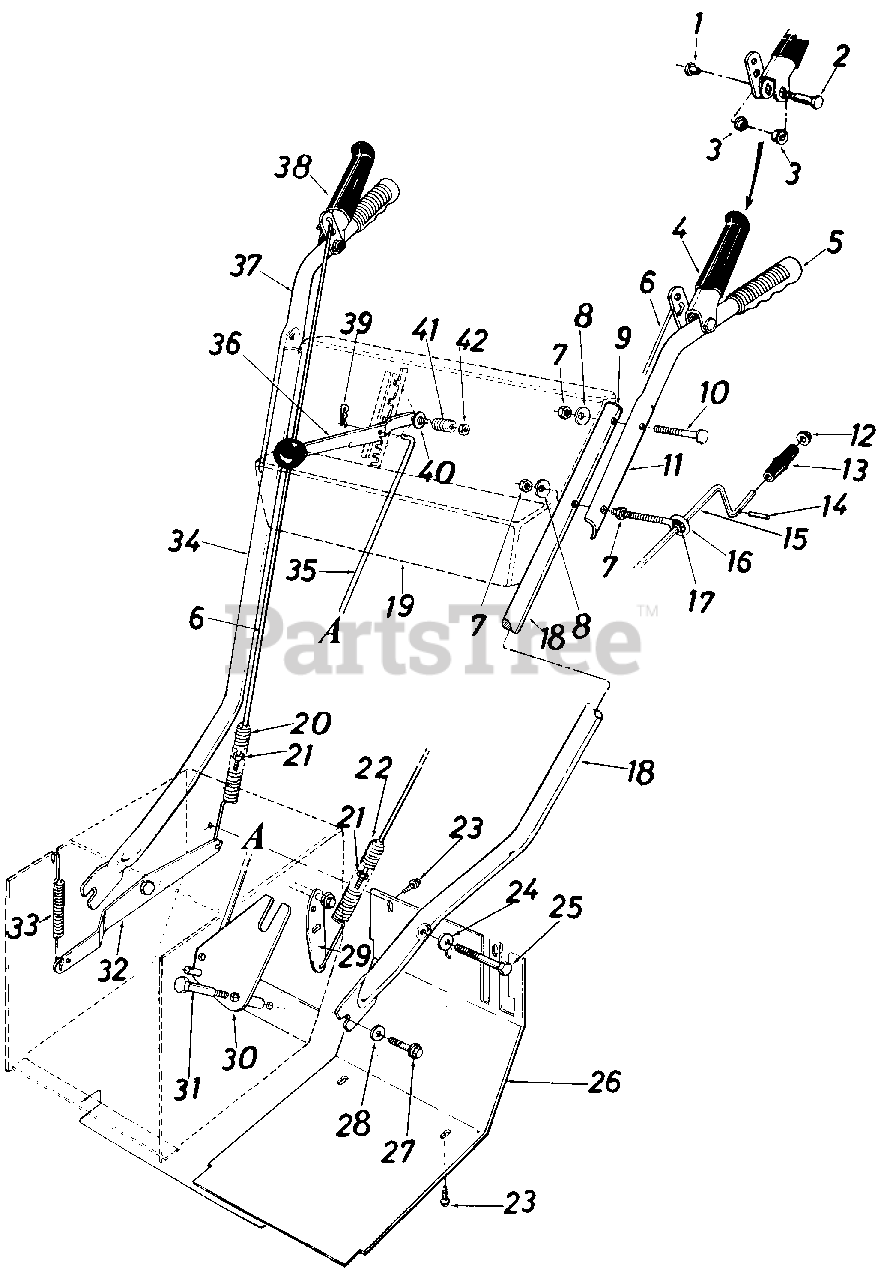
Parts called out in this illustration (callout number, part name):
1	Shld. Nut 1/4-20 Thd.
2	Shld. Bolt .374 Dia. x 1.53" Lg.
3	Hex Flange Plastic Bearing .38" I.D.
4	Clutch Grip Ass'y.-L.H.
5	Grip
6	Lockout Rod
7	Hex Nut 5/16-18 Thd.
8	Bell-Wash. 34" I.D. x .88" O.D.
9	Plastic Plug
10	Curved Carriage Bolt 5/16-18 x 2.0" Lg.
11	Upper Handle-L.H.
12	Push Nut 3/8" Rod
13	Knob 3/8" Rod
14	Roll Pin .12 Dia. x .631" Lg.
15	Chute Crank Ass'y.
16	Eye Bolt 5/16-18 x 5.0" Lg.
17	Plastic Bushing
18	Lower Handle-L.H.
19	Handle Panel Ass'y.
20	Extension Spring .75" O.D. x 5.0" Lg.
21	Hex Ins. L-Nut 1/4-20 Thd.
22	Extension Spring .75" O.D. x 5.0" Lg.
23	Hex Wash. Hd. Self-Tap Scr. 5/16-24 x .50" Lg.
24	Bell-Wash. .40" I.D. x .88" O.D.
25	Hex Bolt 3/8-16 x 2.0" Lg.
26	Frame Cover
27	Pilot Hex Scr. 3/8-16 x .88" Lg.
28	Bell-Wash. .40" kD. x .88" O.D.
29	Drive Clutch Brkt. Ass'y.
32	Auger Clutch Brkt.
33	Extension Spring .38" O.D. x 3.18" Lg.
34	Lower Handle-R.H.
35	Shifting Rod
36	Shift Handle Ass'y.
37	Upper Handle-R.H.
38	Clutch Grip Ass'y.-R.H.
39	Int. Cotter Pin 5/16" Dia.
40	Bell-Wash. .40" I.D. x .88" O.D.
41	Compression Spring
42	Hex Ins. L-Nut 3/8-24 Thd.
